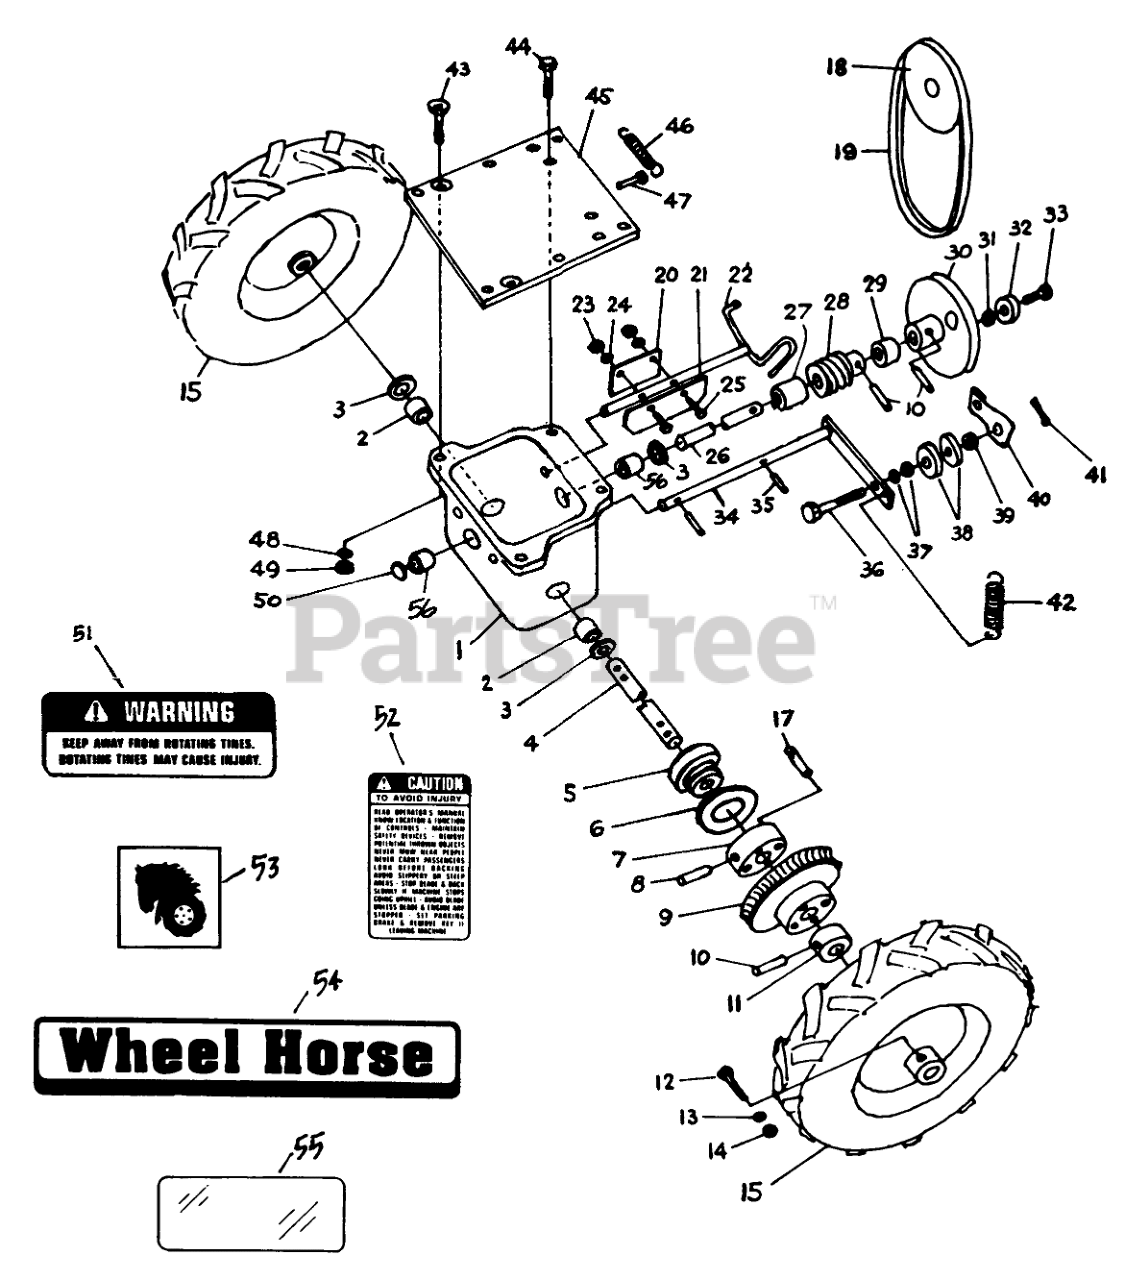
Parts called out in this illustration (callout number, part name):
1	Gear Box
2	Bearing
3	Seal
4	SHAFT-WHEEL
5	Clutch Sleeve
6	Clutch Ring
7	Clutch Collar
9	Worm Gear
10	PIN-SPIROL 5/16 X 1
11	Gear Collar
12	HEX HD CAP SCREW -4
13	Washer
14	Nut
15	Wheel
17	Clutch Pin
18	Engine Pulley
19	BELT-V
20	CLUTCH IN ACTUATOR
21	Clutch "Out" Actuator
22	Gear Clutch Lever
23	Nut
24	Washer
25	Bolt
26	Worm Shaft
27	Long Worm Spacer
28	Worm
29	Short Worm Spacer
30	Pulley
31	LOCKWASHER
32	BEARING-ECCENTRIC
33	BOLT
34	Idler Lever
35	Pin-Roll
36	Bolt
37	LOCKWASHER
37	Hub Spacer
38	Idler Wheel
39	Nut
40	Idler Link
42	SPRING
43	Flathead Screw 5/16-18 x 1 1/4
44	Bolt
45	Top Plate
46	Tension Spring 3/8 x 2 1/2 x .047
47	Groove Pin 1/4 x 1
48	Lockwasher
49	Nut
50	Welch Plug 1 1/4
51	Decal-Warning
52	Decal-Caution
53	DECAL-LOGO
54	5-Speed Decal
55	DECAL-OVERLAY
56	Flanged Bearing
